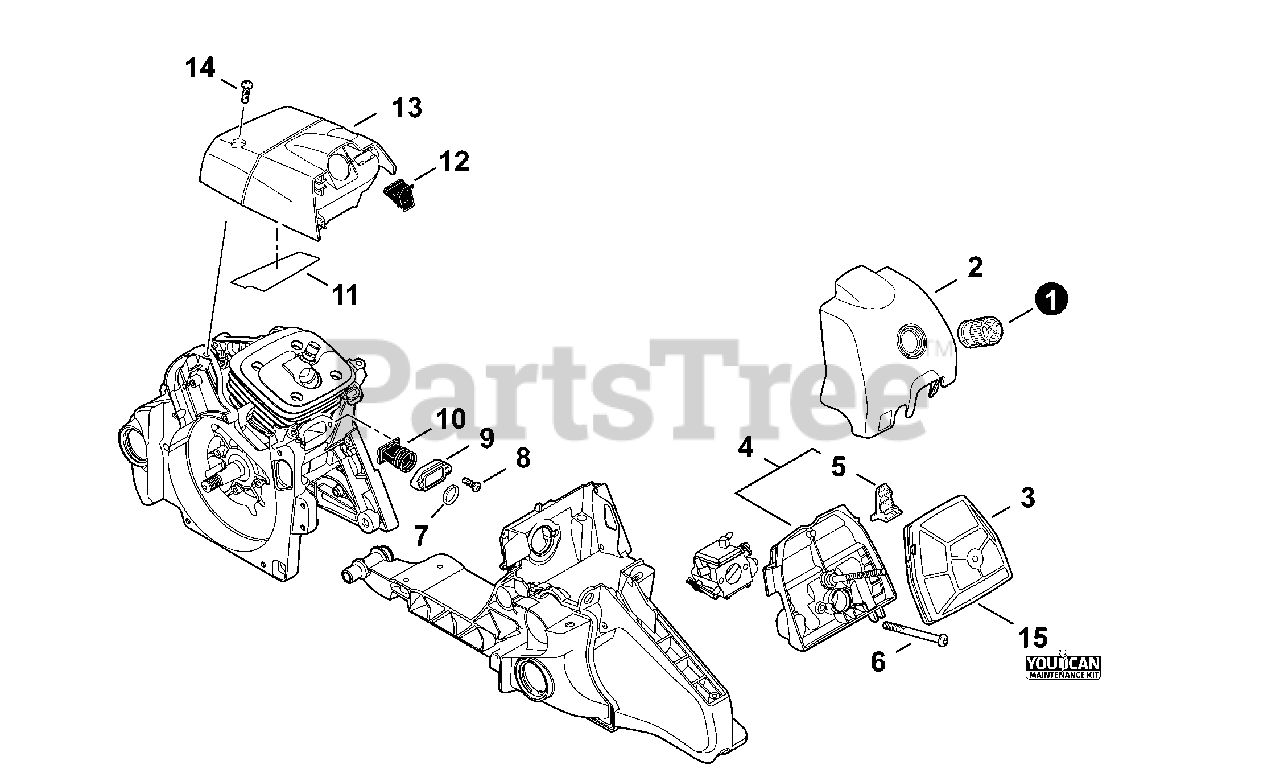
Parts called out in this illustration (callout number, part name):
1	KNOB, AIR FILTER COVER
2	COVER, AIR FILTER
3	FILTER ASSY, AIR
4	CASE, AIR FILTER
5	SHUTTER, AIR
6	BOLT, TORX 5×50
7	COLLAR 18.6×20.4×4
8	BOLT, TORX 5×16
9	HOLDER, BELLOWS
10	BELLOWS, INTAKE
11	SHIELD, HEAT 75×32×0.15
12	PIPE, INTAKE
13	COVER, ENGINE
14	BOLT, TORX 5×16
15	TUNE-UP KIT - YOUCAN™
